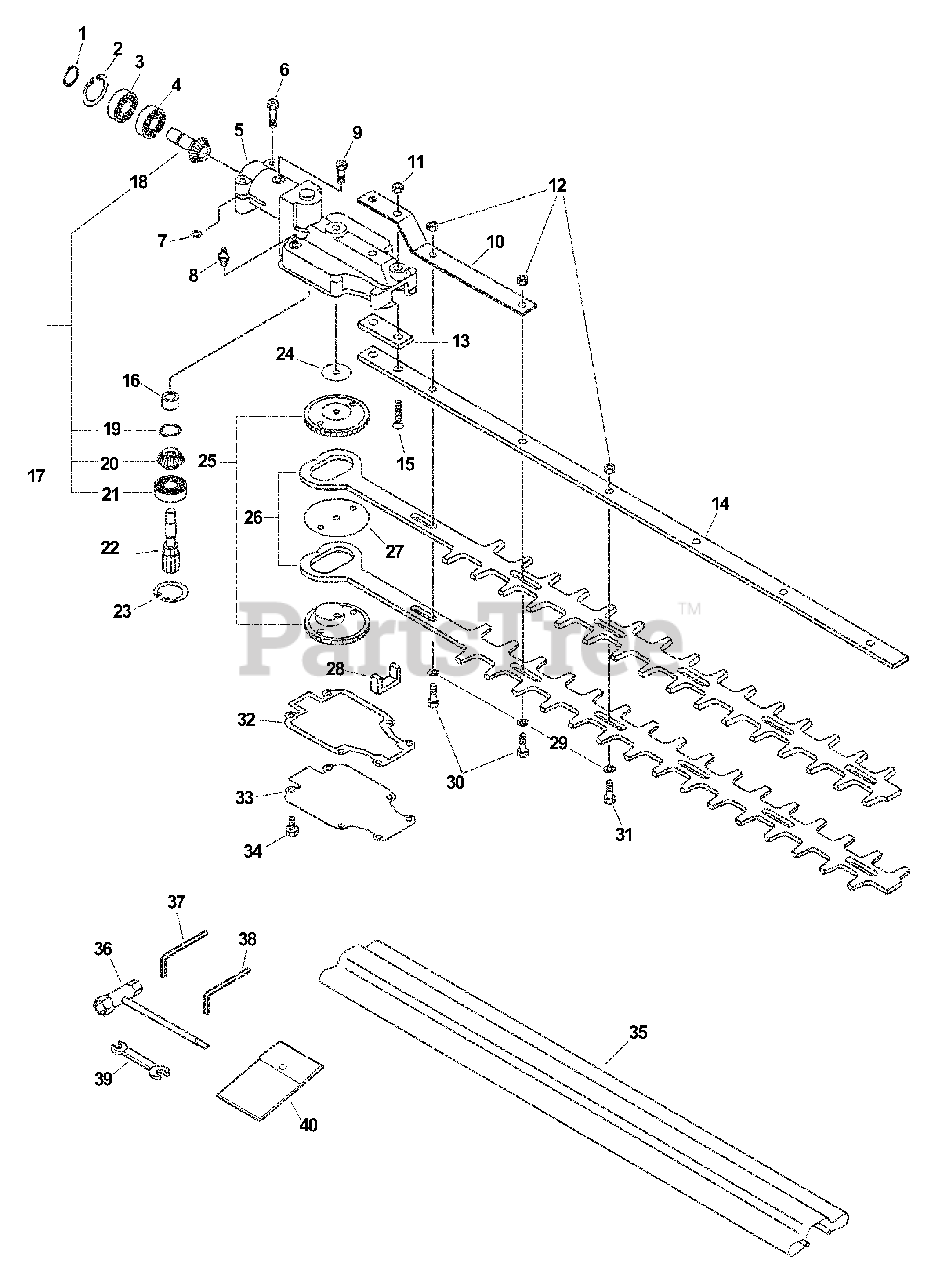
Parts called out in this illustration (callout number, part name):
1	RING, RETAINING - 24
2	RING, RETAINING - 12
3	BEARING, BALL - 6901Z
4	BEARING, BALL - 6901
5	CASE, GEAR - UPPER
6	SCREW - 5X28
8	FITTING, GREASE
9	SCREW - 5X12
10	BRACKET, BLADE
11	LOCKNUT - 6
12	LOCKNUT - 6
13	PLATE
14	SUPPORT, BLADE
15	SCREW - 6X35
16	BEARING, NEEDLE
17	SPUR GEAR ASSY
18	GEAR - BEVEL -- DRIVEN
19	RING, RETAINING
20	GEAR - BEVEL -- DRIVEN
21	BEARING, BALL - 6901
22	GEAR - SHAFT
23	RING, RETAINING - 24
25	GEAR - SPUR
26	BLADE, TRIMMER
28	SEAL, FELT
29	WASHER - 6
31	BOLT - 6
32	GASKET, GEAR CASE
33	LID, GEAR CASE
34	SCREW - 4X12
35	COVER, BLADE
36	T-WRENCH - 17X19mm
37	HEX KEY - 4mm
38	HEX KEY - 3mm
39	SPANNER - 8X10mm
40	BAG, TOOL
